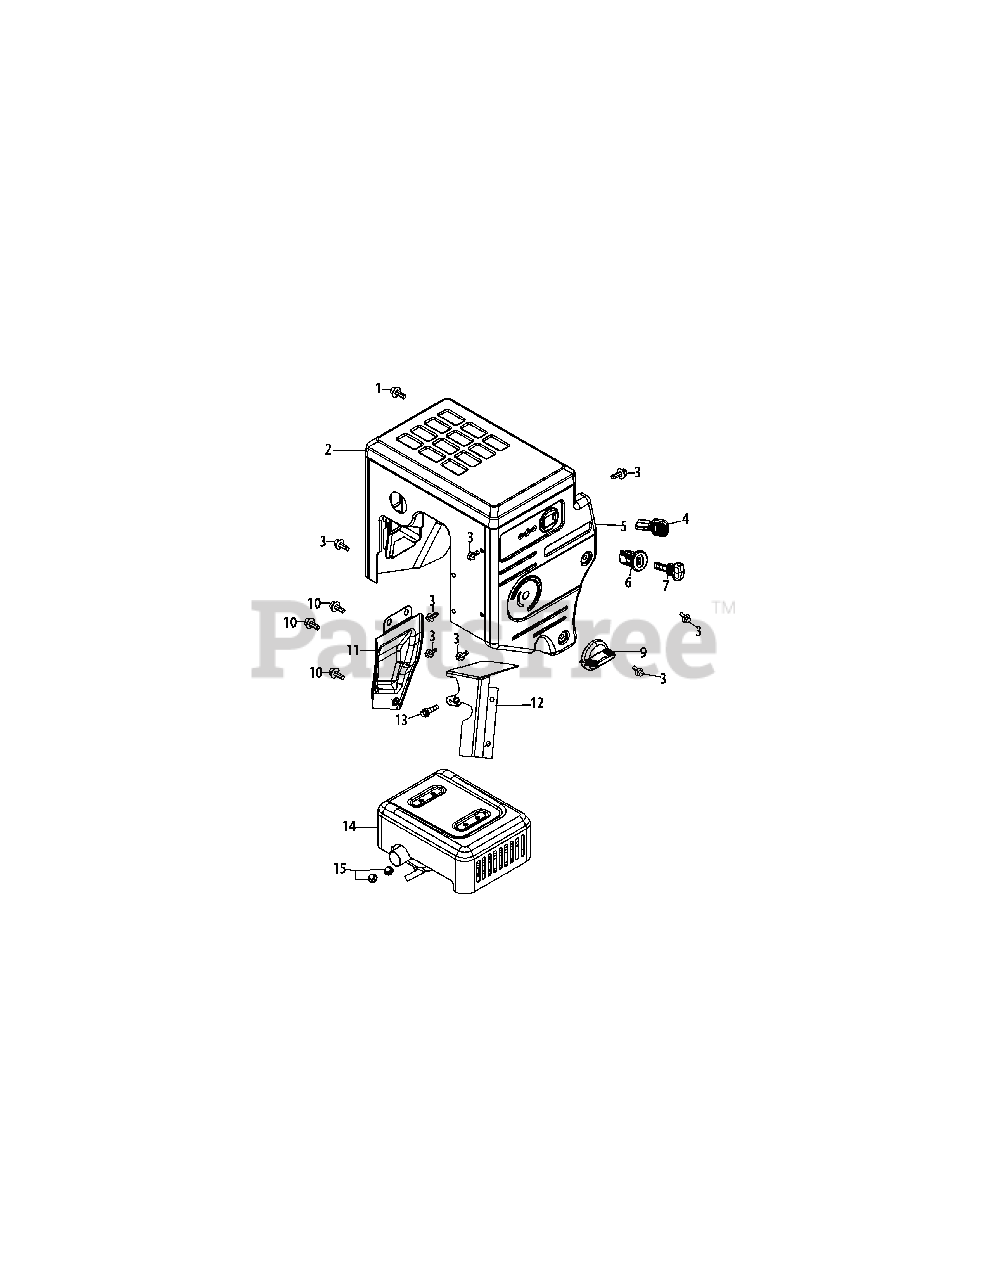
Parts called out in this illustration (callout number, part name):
1	Bolt M6×14
2	Muffler Shield
3	Bolt M6×12
4	Throttle Control Knob
5	Control Panel
6	Key Switch Base
7	Key
9	Choke Knob
10	Bolt M6×10
11	Muffler Baffle
12	Heat Shield
13	Bolt M6×16
14	Muffler Assembly
15	Nut M8
